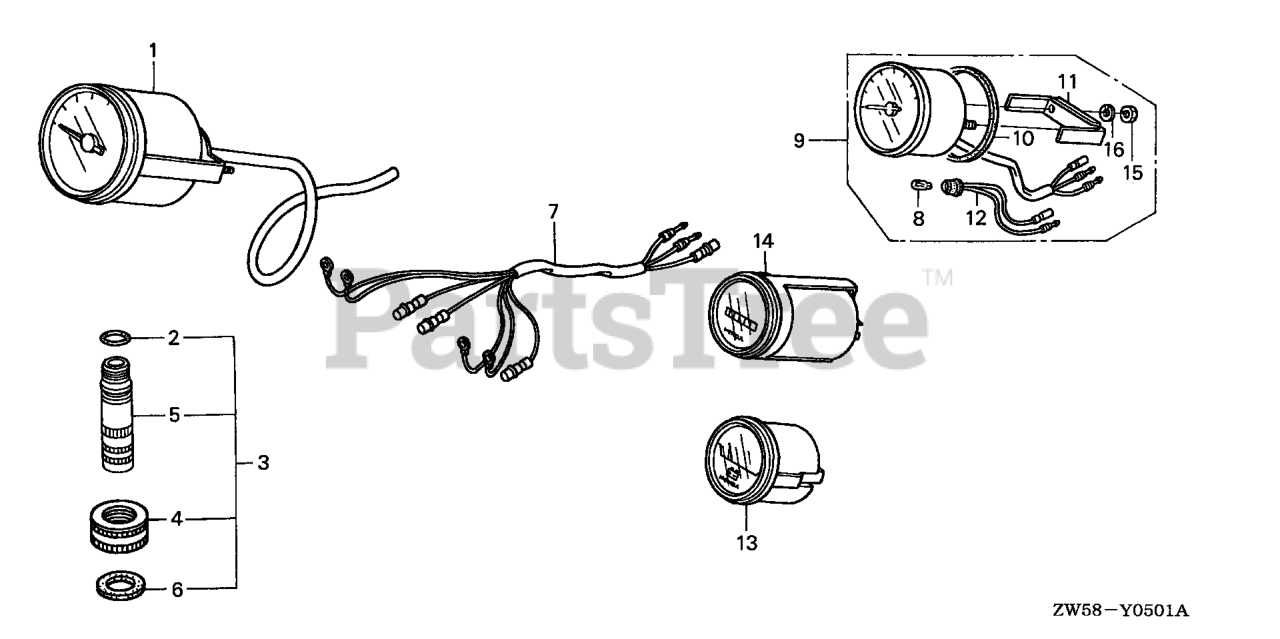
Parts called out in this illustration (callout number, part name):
1	SPEEDOMETER KIT
2	O-RING (11.8X2.4)
3	JOINT ASSY., HOSE
4	NUT, WATER MOUTH Use from Frame SN 1000929.
5	JOINT ASSY., HOSE
6	SEAT, WATER MOUTH Use from Frame SN 1000929.
7	HARNESS ASSY., METER (B)
8	BULB, WEDGE BASE (T10) (12V 1.7W) (STANLEY)
9	TACHOMETER ASSY.
10	GASKET
11	BRACKET (TO 1015209) (FROM 1015210)
12	SOCKET (TO 1015209) (FROM 1015210)
13	METER ASSY., VOLT (NOT AVAILABLE: USE 37453-ZW5-000ZA)
14	METER ASSY., HOUR L.C.D.
15	NUT, HEX. (5MM)
16	WASHER, SPRING (5MM)
